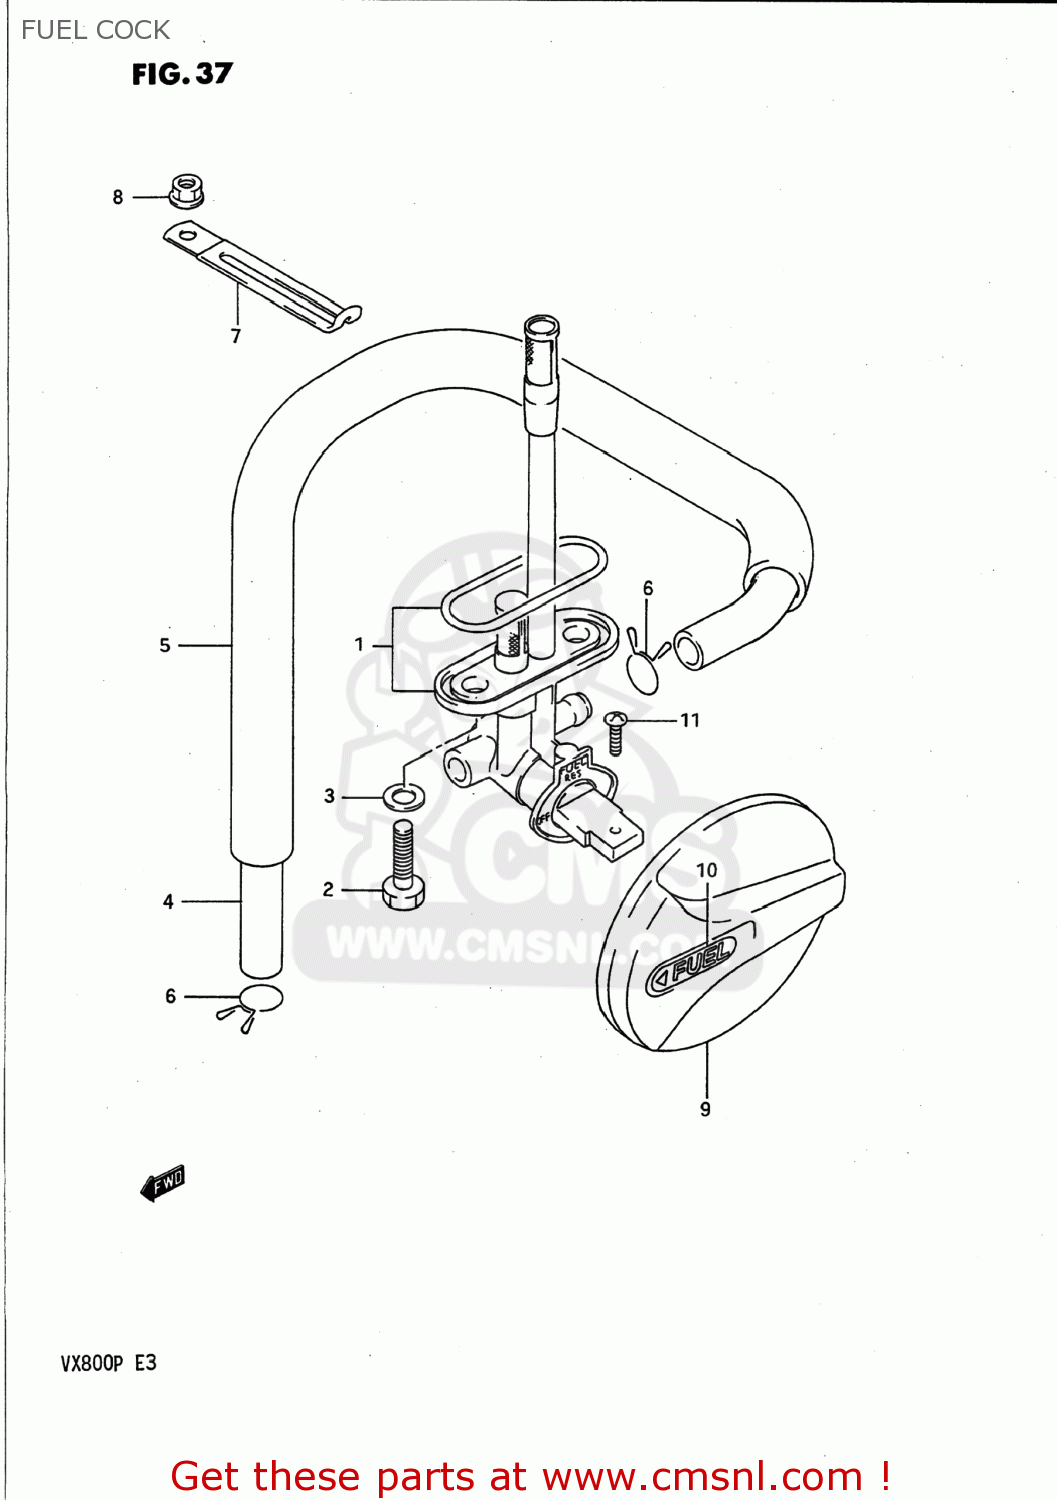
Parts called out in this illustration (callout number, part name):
1	COCK SET,FUEL
2	BOLT(6X20)
3	GASKET(6.4X11.5X0.8) (NAS)
4	HOSE(7X11X600)
5	PROTECTOR,FUEL HOSE
6	CLIP
7	CLAMP
8	NUT
9	LEVER,FUEL COCK
10	LABEL,FUEL COCK LEVER
11	SCREW
